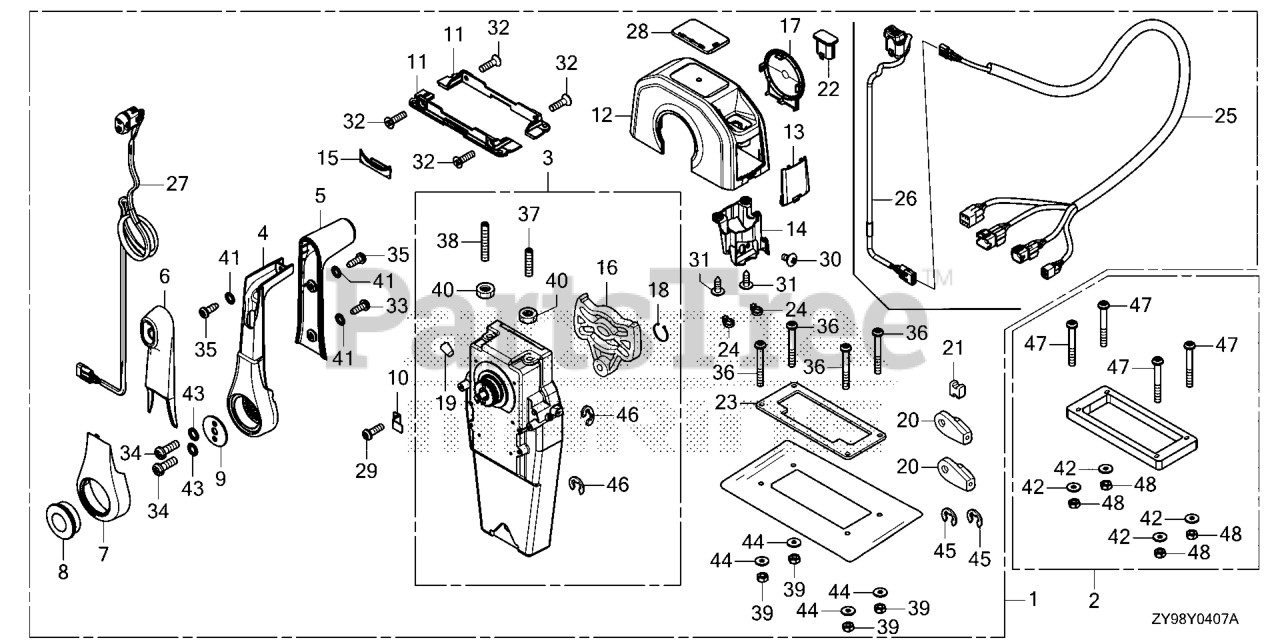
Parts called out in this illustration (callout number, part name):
1	BOX KIT, REMOTE CONTROL (TOP MOUNT SINGLE) (TROLLING CONTROL)
1	BOX KIT, R/C
1	BOX KIT
2	SPACER KIT, REMOTE CONTROL BOX (TOP MOUNT SINGLE)
3	HOUSING ASSY., L. (INNER) (TOP MOUNT) (NOT AVAILABLE)
4	HANDLE, REMOTE CONTROL (NOT AVAILABLE)
5	COVER, GRIP
6	GRIP
7	COVER, LEVER (NOT AVAILABLE)
8	BUTTON, THROTTLE (NOT AVAILABLE)
9	PLATE, HANDLE
10	PLATE, CABLE CLAMP
11	BRACKET, REMOTE CONTROL HOUSING (NOT AVAILABLE)
12	HOUSING, SINGLE REMOTE CONTROL BOX (NOT AVAILABLE)
13	PLUG, SINGLE HOUSING (NOT AVAILABLE)
14	GUIDE, SINGLE WATER (NOT AVAILABLE)
15	HOUSING, LEAD (NOT AVAILABLE)
16	PLATE, DWELL
17	COVER, HOUSING SIDE (NOT AVAILABLE)
18	RING, SNAP (NOT AVAILABLE)
19	GROMMET (NOT AVAILABLE)
20	TERMINAL, CABLE
21	SPACER, CABLE CLAMP
22	CAP, BLANK (NOT AVAILABLE)
23	GASKET, SINGLE
23	GASKET T/S
24	BAND, TY-RAP (POWER TRIM-TILT) (NOT AVAILABLE)
25	HARNESS SUB-ASSY., REMOTE CONTROL (NOT AVAILABLE)
26	SWITCH ASSY., TROLLING CONTROL (NOT AVAILABLE)
27	SWITCH ASSY., POWER TRIM-TILT (NOT AVAILABLE)
28	MARK, REMOTE CONTROL (SINGLE) (NOT AVAILABLE)
29	SCREW, PAN (5X16)
30	SCREW, TRUSS (5X10) (NOT AVAILABLE)
31	SCREW, TRUSS (5X16) (TAPPING) (NOT AVAILABLE)
32	SCREW, PAN (5X18)
33	SCREW, PAN (5X14) (TAPPING) (NOT AVAILABLE)
34	SCREW, PAN (6X18)
35	SCREW, PAN (5X14) (TAPPING)
36	SCREW, PAN (5X40)
37	BOLT, STOPPER (F) (NOT AVAILABLE)
38	BOLT, STOPPER (R) (NOT AVAILABLE)
39	NUT, HEX. (5MM)
40	NUT (6MM) (LOOSE PARTS)
41	WASHER, LOCK (5MM)
42	WASHER, PLAIN (5MM)
43	WASHER, LOCK (6MM)
44	WASHER, PLAIN (5MM)
45	E-RING (6MM) (LOOSE PARTS)
46	E-RING (6MM) (LOOSE PARTS)
47	SCREW, PAN (5X65)
48	NUT, HEX. (5MM)
